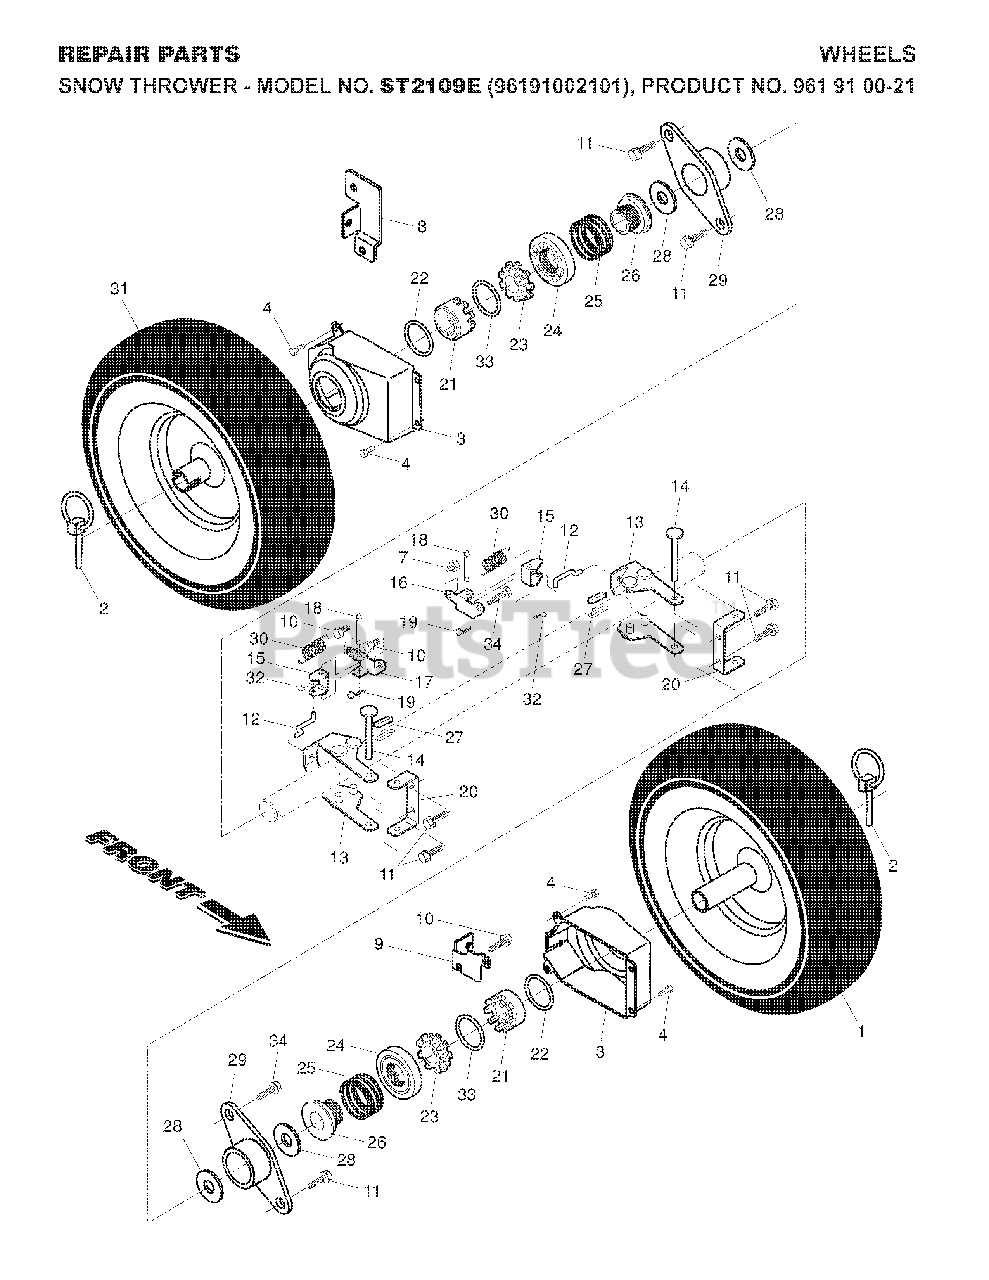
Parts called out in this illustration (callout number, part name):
1	16 X 4.8 LH WHEEL GREY
2	PIN KLIK, 1/4
3	COVER, POWER STEERING
4	SCREW, HEX HEAD, TAPPING
7	SCREW 14-20 X 5/8
8	BRACKET, STEERING CABLE RH
9	BRACKET.STEER.CABLE.LH.BZP
12	LINK.STEER.YOKE
13	YOKE, STEERING
14	PIN, STEERING LEVER
15	BELLCRANK.STEER
16	CONTROL SHAFT
17	BRKT.STEER.PIVOT.RH
18	PIN, STEERING BELLCRANK
19	RETAINER CLIP PM
20	BRACKET.STEER.PNT.BLACK
21	DRIVER WHEEL
22	RING, WIRE RETAINER
23	LOBE WHEEL
24	SLIDE.CLUTCH
25	SPRING, CLUTCH SLIDE
26	LOBE.AXLE
27	KEY, SQUARE 1/4 X .875
28	WASHER TRUST 1"
29	BEARING, AXLE
30	SPRING LATCH
31	16 X 4.8 RH WHEEL
32	RETAINER CLIP
